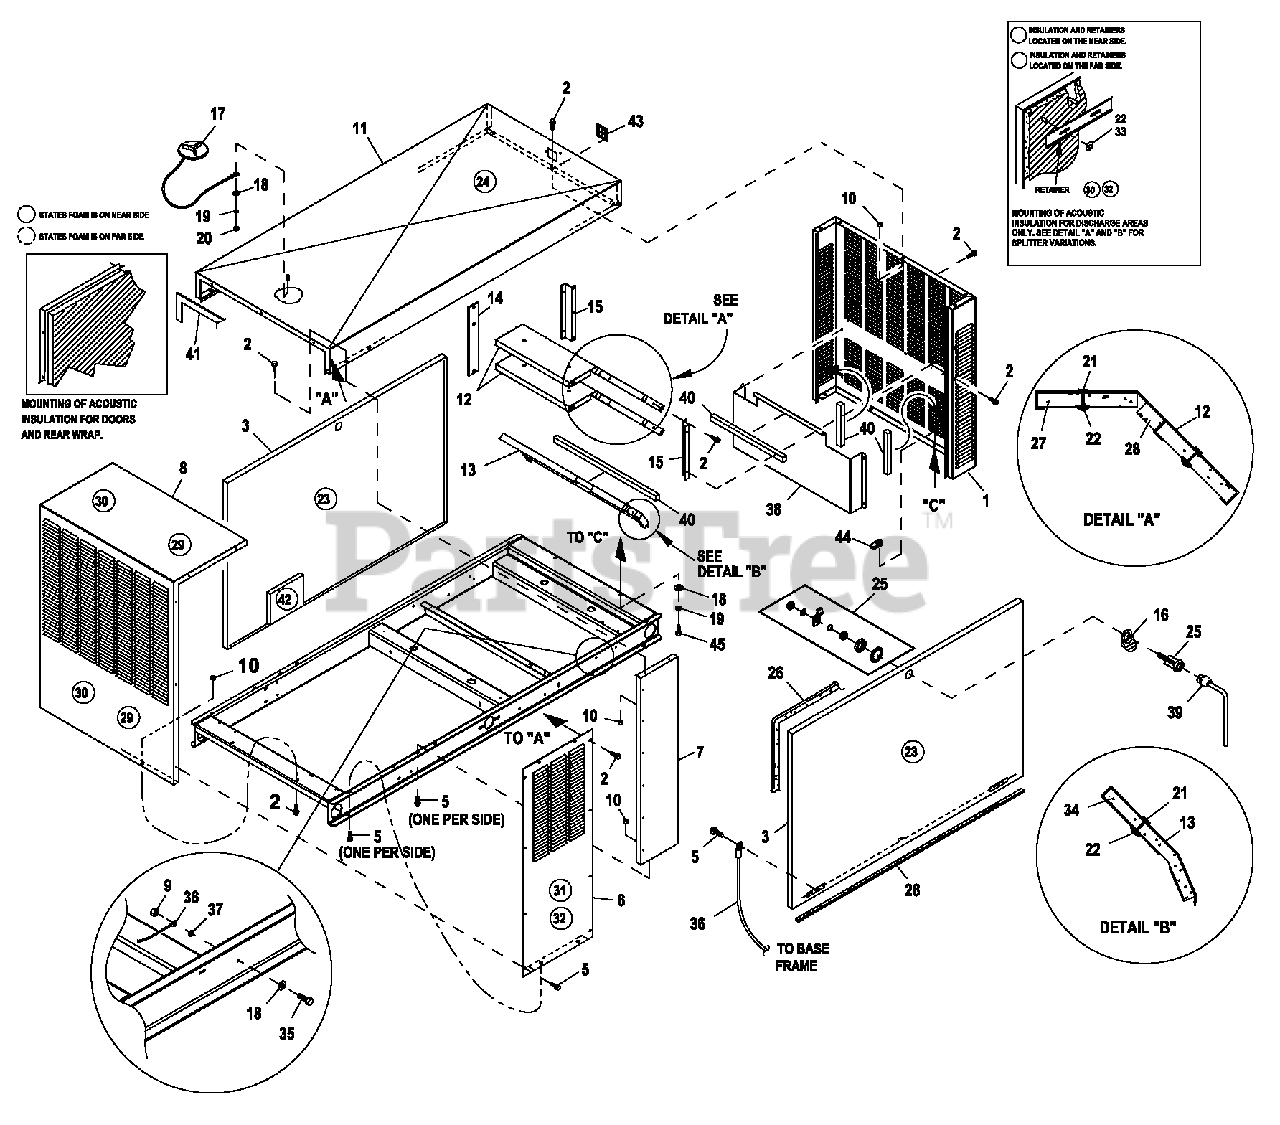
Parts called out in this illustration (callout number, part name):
1	REAR WRAP C2 G2 60KW
2	SCREW THF M6-1 X 16 N WA Z/JS
3	DOOR C2
4	RIVET POP.1875 X .450 SS
5	SCREW TH-FRM M6 W/CAP SHKPRF W
6	DUCT DSCHRG LH&RH
7	FRONT CORNERS C2
8	DUCT DISCHARGE C2
9	NUT HEX M 6X1.0 G8 YELCHR
10	NUT HEX LOCK M6-1.0 SS NY INS
11	ROOF C2
12	SLITTER C4
13	SPLITTER LOWER C4
14	SPLITTER STINGER C2
15	SUPPORT SPLITTER LHC2
16	PULL TAB DOOR LOCK SS
17	ASSEMBLY COVER ACCESS
18	WASHER FLAT 1/4-M6 ZINC
19	WASHER LOCK M6-1/4
20	NUT HEX 1/4-20 STEEL
21	INSULATION RETAINMENT HANGER
22	WASHER SELF LOCKING DOME #4-40
23	INSULATION DOOR C2
24	INSULATION ROOF TOP
25	VISE-ACTION LATCH SLOTTED CIR
26	GASKET EXTRUDED TRIM (328" LG)
27	INSULATION SPLITTER
28	INSULATION SPLITTER
29	INSULATION DUCT
30	RETAINER INSULATION (820)
31	INSULATION DUCT SIDES
32	RETAINER INSULATION (450)
33	WASHER SELF LOCKING DOME #8-32
34	INSULATION LOWER SPLITTER
35	SCREW HHC M6-1.0X20 G8.8
36	ASSY WIRE 14AWG GRN/YEL
37	WASHER SHAKEPROOF INT 1/4
38	DEFLECTOR INTAKE 2.4L G2 TURBO
39	KEY VISE-ACTION LATCH SLOT CIR
40	TAPE FOAM 1X1 (71.0"LG)
41	STRIP SEALANT 1/8X 1 (44.52"LG)
42	FOAM 300 X 300 THERMAL ACO
43	RF COVER PLATE-PLASTIC-BISQUE
44	NUT UM6-1.0 GEOMET
45	SCREW HHFC M6-1.0X 2 0 G8.8
